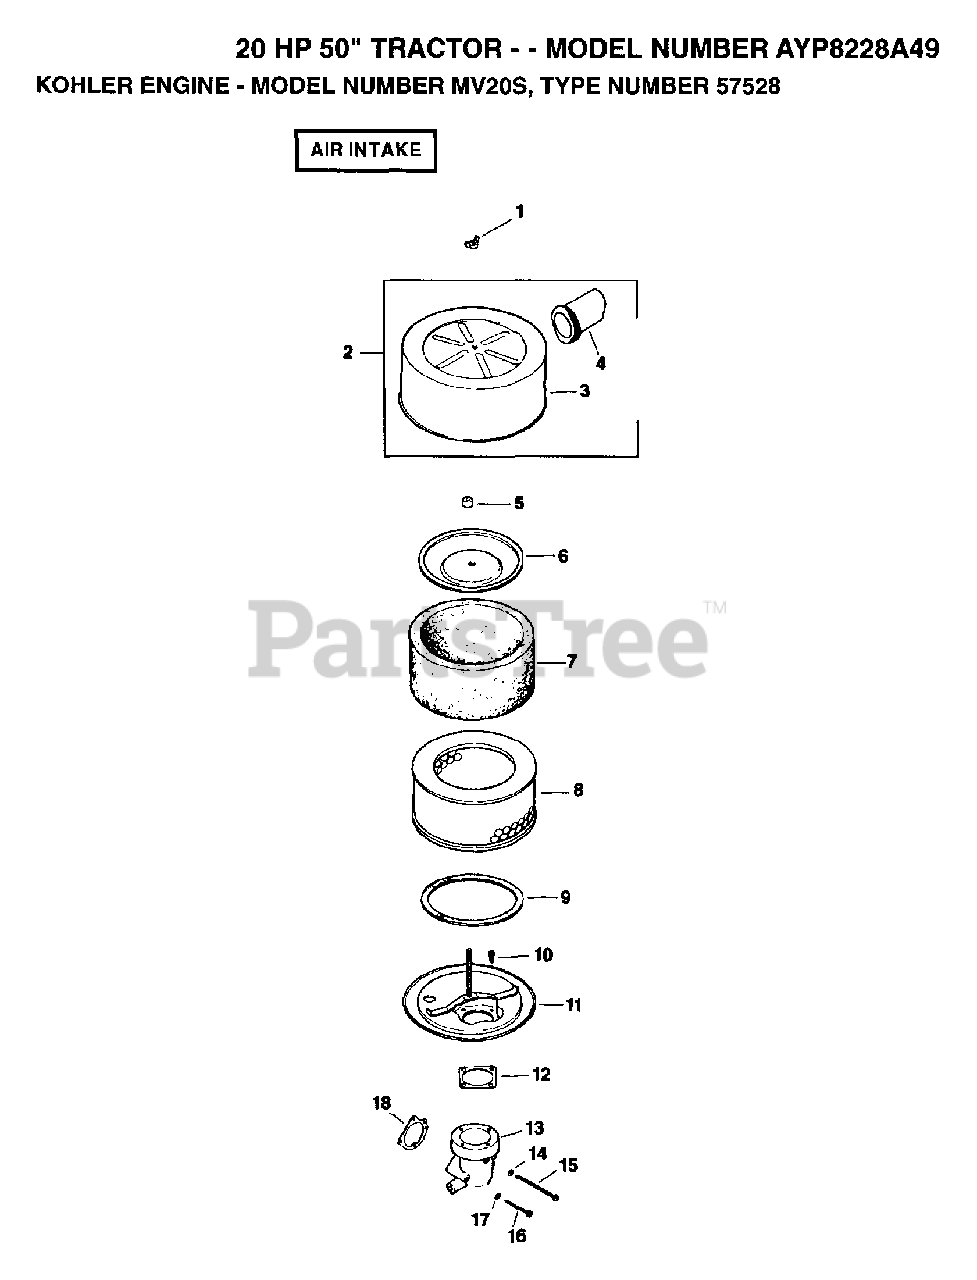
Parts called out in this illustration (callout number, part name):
1	WING NUT
3	COVER AIR CLEANER
4	TUBE AIR INTAKE
5	SEAL ELEMENT
6	COVER AIR CLEANER ELEMENT
9	SEAL
10	SCREW
12	GASKET
13	ELBOW AIR INTAKE
14	WASHER
15	SCREW
17	WASHER
18	GASKET, AIR CLEANER
